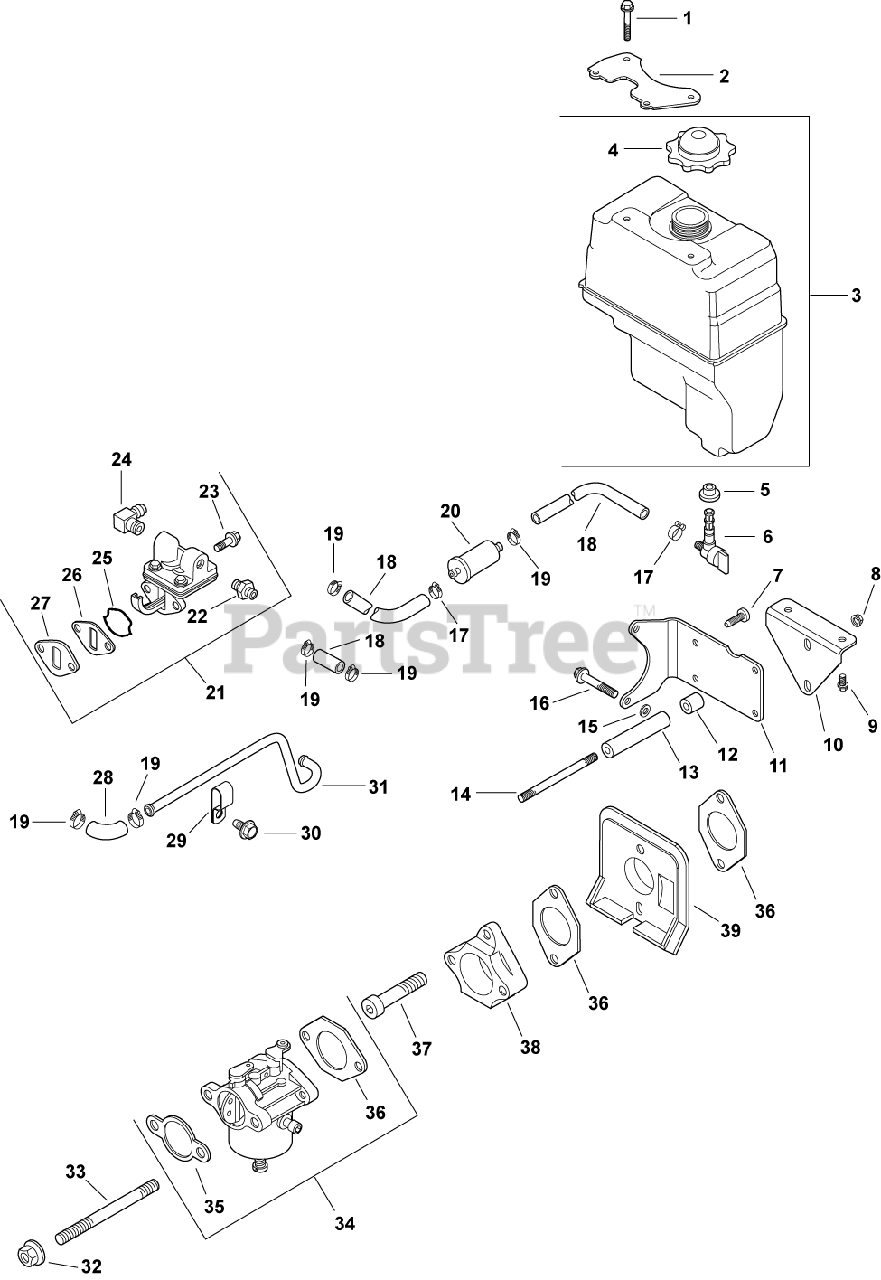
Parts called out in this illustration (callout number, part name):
1	SCREW,FLG THD FRM M6X1.0X25-(#25086395S)
2	BRACKET, FUEL TANK
3	KIT, FUEL TANK
4	CAP, FUEL TANK
5	BUSHING, FUEL TANK
6	VALVE, FUEL SHUT-OFF
7	SCREW, LBD SKT M6x1.0x20-(#25086403S)
8	NUT, FLG M8X1.25
9	SCREW, FLG M6X1.0X12
11	BRACKET, FUEL TANK
13	SPACER, FUEL TANK
14	STUD, M8X1.25X133-USE 25 755 54-S
15	WASHER, FLAT 11/32"
16	SCREW, FLG M8X1.25X50
17	CLAMP, BAND SPRING HOSE-(#2523737S)
18	HOSE,LW PERM.FUEL 24.00"-USE 25 111 81-S
19	CLAMP, HOSE (KM)-USE 25 237 31-S
20	FILTR,FUEL 75 MICRON (GRAVTY FEED)
21	KIT, FUEL PUMP
22	KIT, STRAIGHT FITTING
23	SCREW,FLG THD FRM M6X1.0X20-(#25086396S)
24	CONNECTOR, 90 DEG. HOSE
25	O-RING, FUEL PUMP
26	SPACER, FUEL PUMP
27	GASKET, FUEL PUMP
28	HOSE, FUEL LOW-PERMEATION
29	CLIP, TUBE & WIRING (KM)
30	SCREW, FLG THD FRM M5X.8X10
31	LINE, FUEL - DISCONTINUED
32	NUT, FLG M6X1.0
33	STUD,M6X1.0X116
34	KIT, CARBURETOR
35	GASKET, AIR CLEANER BASE
36	GASKET, CARBURETOR
37	SCREW, SKT CAP M6X1.0X35
38	ADAPTER, CARBURETOR
39	DEFLECTOR, HEAT
